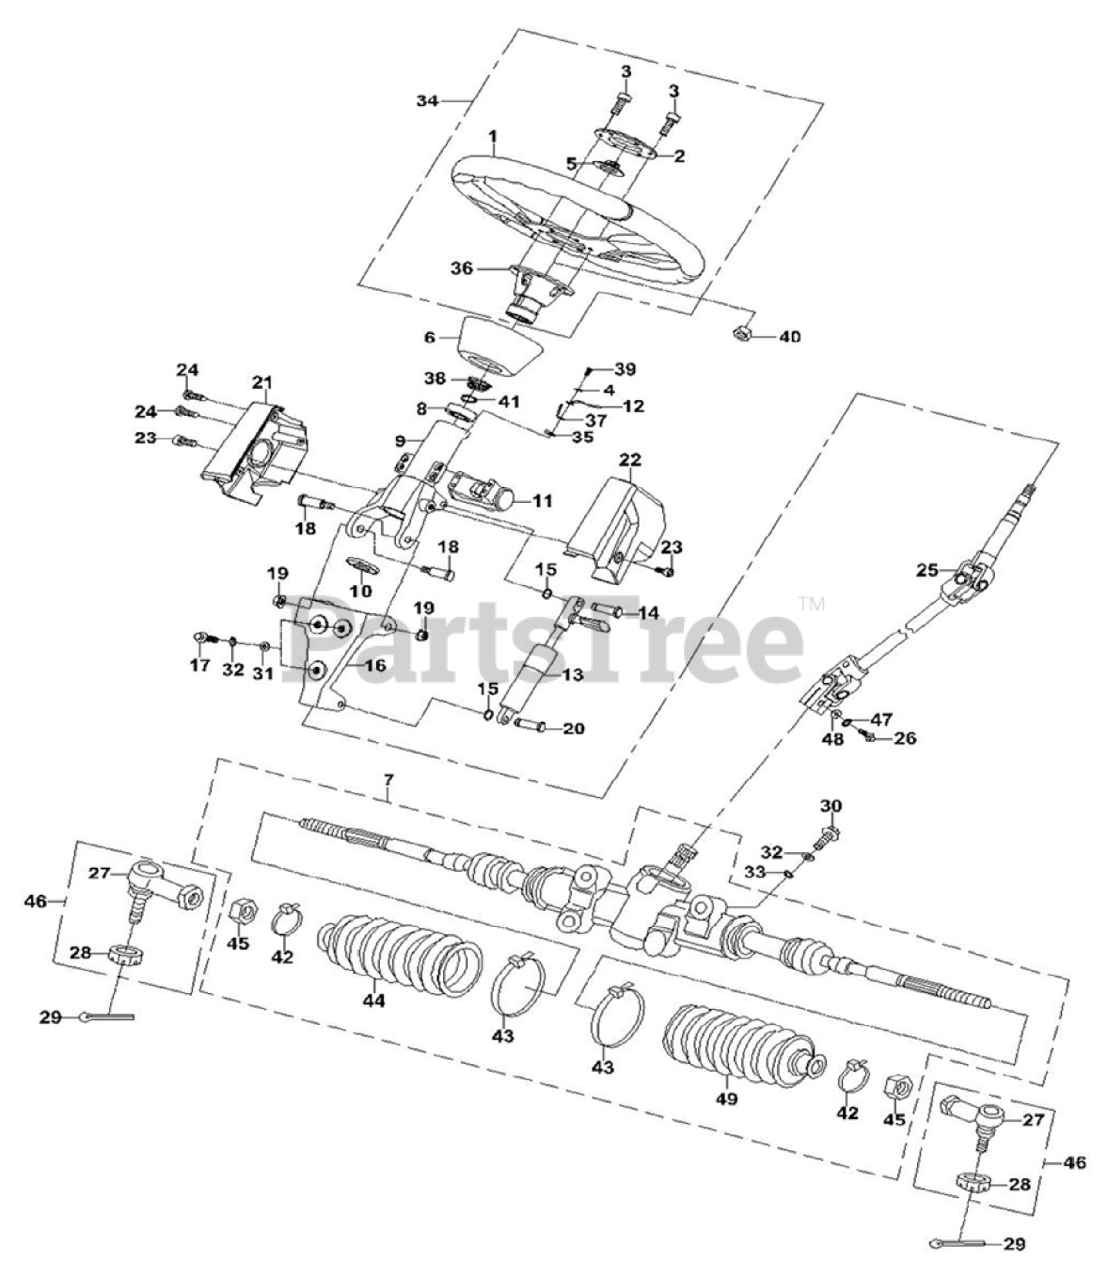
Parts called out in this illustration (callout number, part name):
1	Steering wheel assembly
2	STEERING WHEEL CAP
3	Hexagon Socket Bolt
4	WASHER - HORN
5	SWITCH - HORN
6	STEERING POST COVER KIT
7	STEERING ASSEMBLY
8	BEARING 6003-2RZ
9	STEERING COLUMN COVER
10	BEARING 6805
11	MAIN SWITCH
12	HORN GROUND WIRE
13	GAS SPRING WHEEL ASSEMBLY
14	SHOULDER COTTER PIN 8x34
15	CLIP
16	MOUNTING BRACKET
17	Hexagon Flange Bolt M10x1.25x25
18	SHOULDER BOLT M6x10x2.5x30.5
19	LOCK NUT M6
20	SHOULDER COTTER PIN 8x45
21	STEERING COLUM COVER III
22	STEERING COLUM COVERII
23	BOLT HExAGON SOCKET FLANGE M6x12
24	SCREW CROSS HEAD SELF DRILLING ST3.9x13
25	SHAFT WHEEL ASSEMBLY
26	Hexagon Flange Bolt M8x30
27	Ball joint assembly
28	hexagon thin slotted nut M12x1.25
29	COTTER PIN 2x30
30	BOLT HExAGON FLANGE HEAD M10x1.25-40
31	Washer 10x32x5
32	Spring Washer10
34	WHEEL ASSEMBLY
35	HORN INSULATION WASHER
36	CONNECTING WHEEL FLANGE
37	HORN REED SWITCH
38	SPRING HORN SWITCH
39	SCREW CROSS HEAD M3x12
40	LOCK NUT M12x1.25
41	CLIP D0=17
42	Spring Clamp
43	Dirt-proof Boot Clamp
44	Dirt-proof Boot
45	NUT M14x1.5
46	BALL JOINT ASSEMBLY
47	Spring Washer-8
49	Dirt-proof Boot
50	CROSS RECESSED PAN HEAD SCREW M5 X 16
53	INSTRUMENT PANEL SEAL
